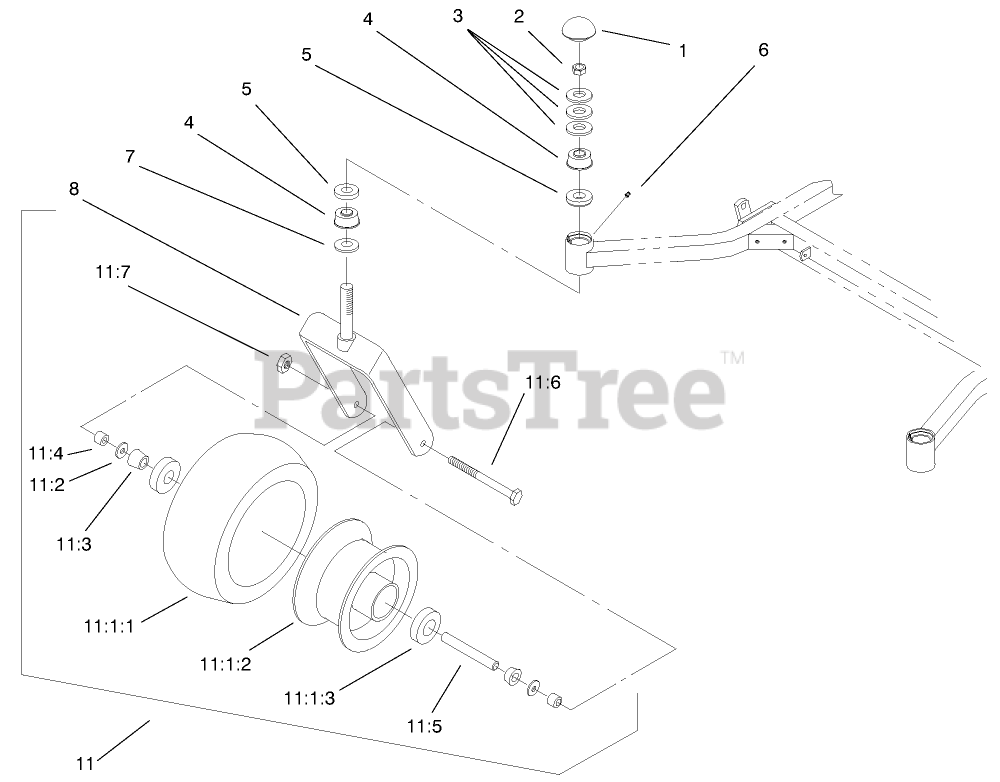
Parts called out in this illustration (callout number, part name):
1	Cap-Grease
2	LOCKNUT
3	Washer-Bellevue
4	BEARING-CONE, TAPERED
5	BEARING-CUP, TAPERED
6	Plug
7	Seal-Grease
8	Caster
11	Caster Wheel ASM
11:1	Wheel & Tire ASM
11:1:1	Tire
11:1:2	Wheel
11:1:3	BEARING-ROLLER, CUP
11:2	Seal-Bearing
11:3	BEARING-CONE
11:4	Spacer-Bearing
11:5	Spacer
11:6	Screw-HH
11:7	Nut-Lock
